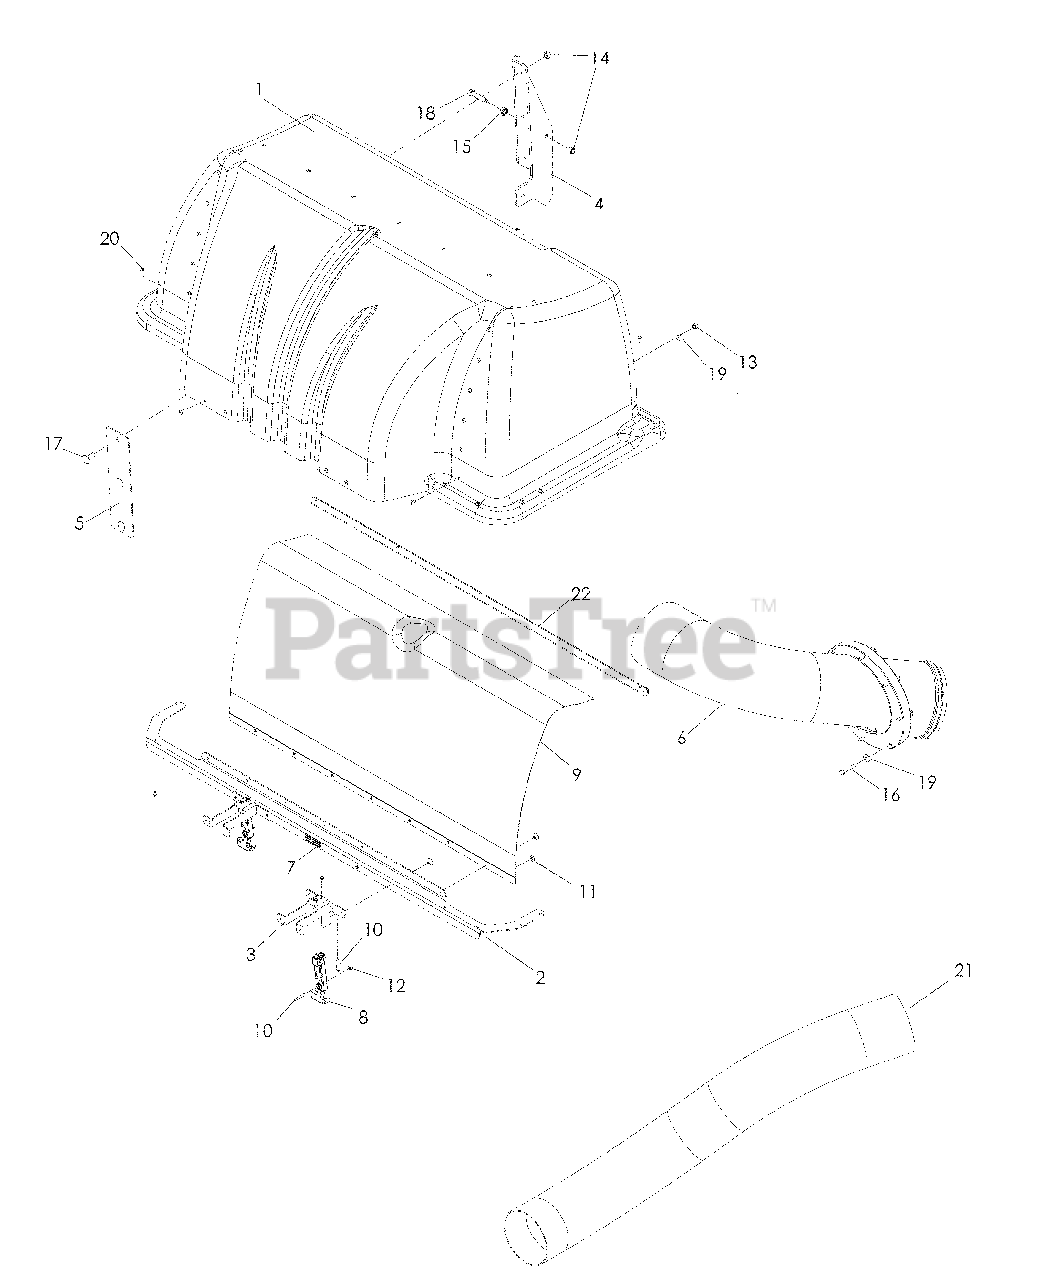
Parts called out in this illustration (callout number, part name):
2	HOOD SUPPORT
3	SUPPORT, DRAW LATCH
4	HOOD HINGE
5	MOUNT PLATE
6	INLET TUBE
7	DECAL, VENTILATION
8	DRAW LATCH
9	MESH, POLY DIAMOND
10	SCREW #10-24 x 11/8
11	WASHER #10
12	NUT #10-24 NYLOC
13	NUT ¼-20 NYLOC
14	NUT 3/8-16 NYLOC
15	NUT 3/8-16 WHIZLK
16	HCS ¼-20 x 1¾
17	RHSNB 3/8-16 x 1
18	HCS 3/8-16 x 1¾
20	WASHER #10
22	HOOD SUPPORT, REAR
